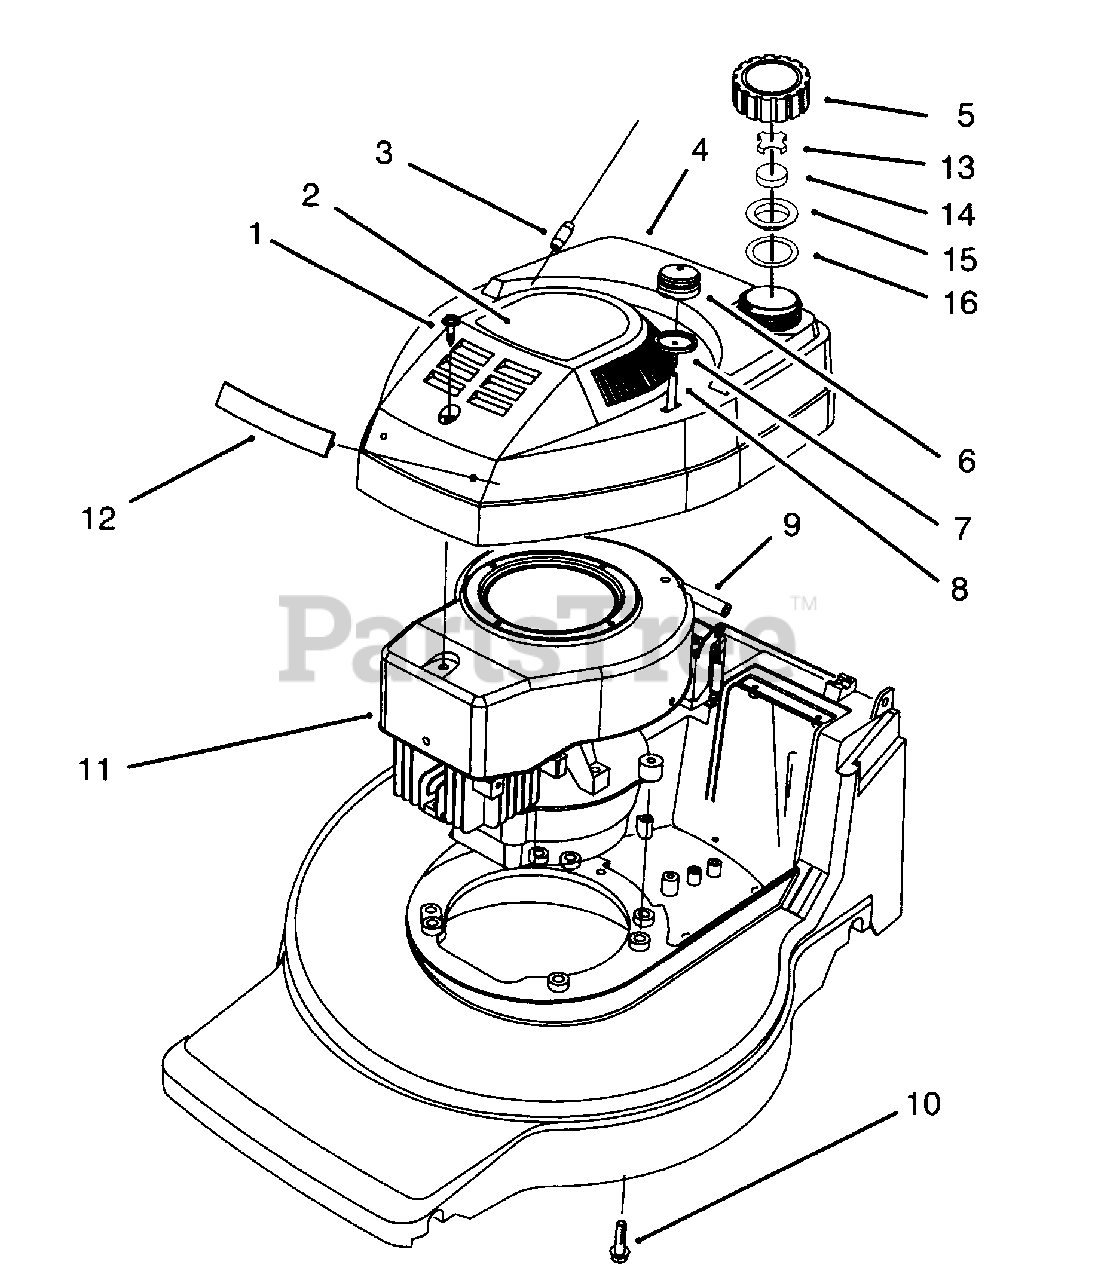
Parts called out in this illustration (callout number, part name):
1	Screw-Sems
2	Decal-Shroud
3	Rope-Stop
4	Tank Shroud Assembly
5	Cap-Gas (Incl. Ref. #13-16)
6	Bulb-Primer
7	Body-Primer
8	Hose-Primer
9	Line-Gas
10	Screw-Engine
12	Decal-Shroud
14	Baffle-Foam
